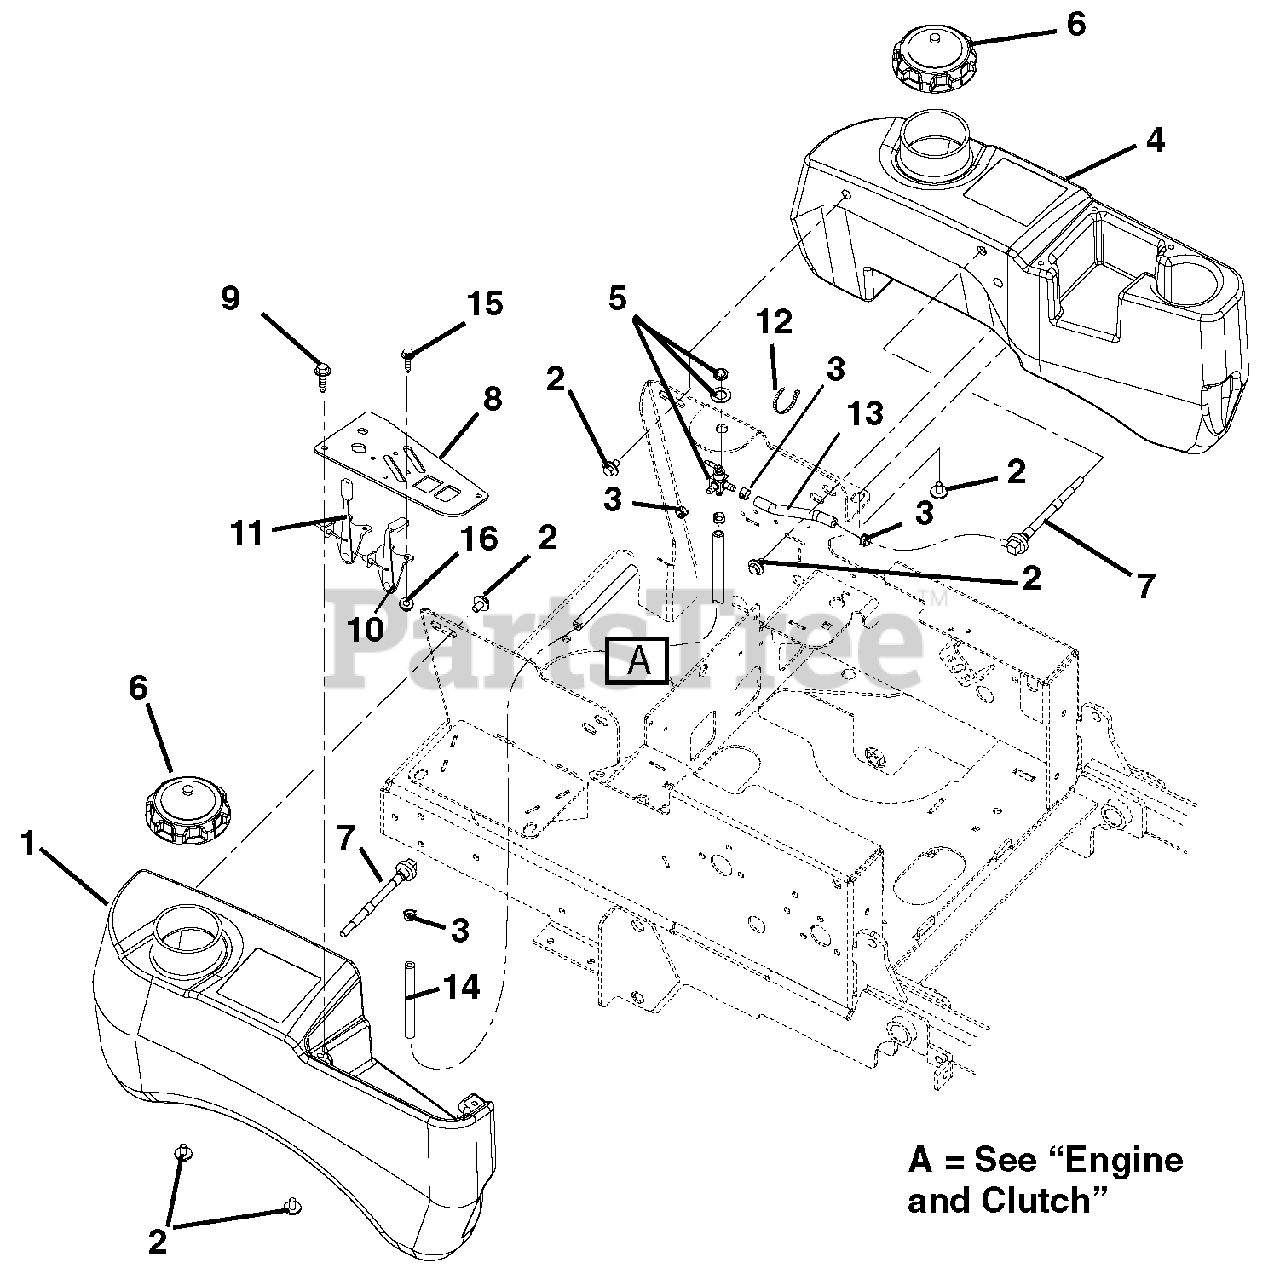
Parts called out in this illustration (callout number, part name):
1	Tank, Right Hand Fuel
2	Bolt, SEMS .31-18 x .62
3	Clamp, Fuel Line
4	Tank, Left Hand Fuel
5	Valve, Fuel
6	Cap, Fuel
7	Assembley, Small Tank Fuel Pick-up
8	Panel, Control
9	Screw, Machine 10-24 x .50
10	Cable, Throttle
11	Cable, Choke
12	Cable Tie
13	Hose, .25 Low-PERM Bulk Gas
14	Hose, .25 Low-PERM Bulk Gas
15	Screw, Machine 10-24 x .50 Hex Washer Head
16	Nut, Locking-Nylon 10-24 with Insert
